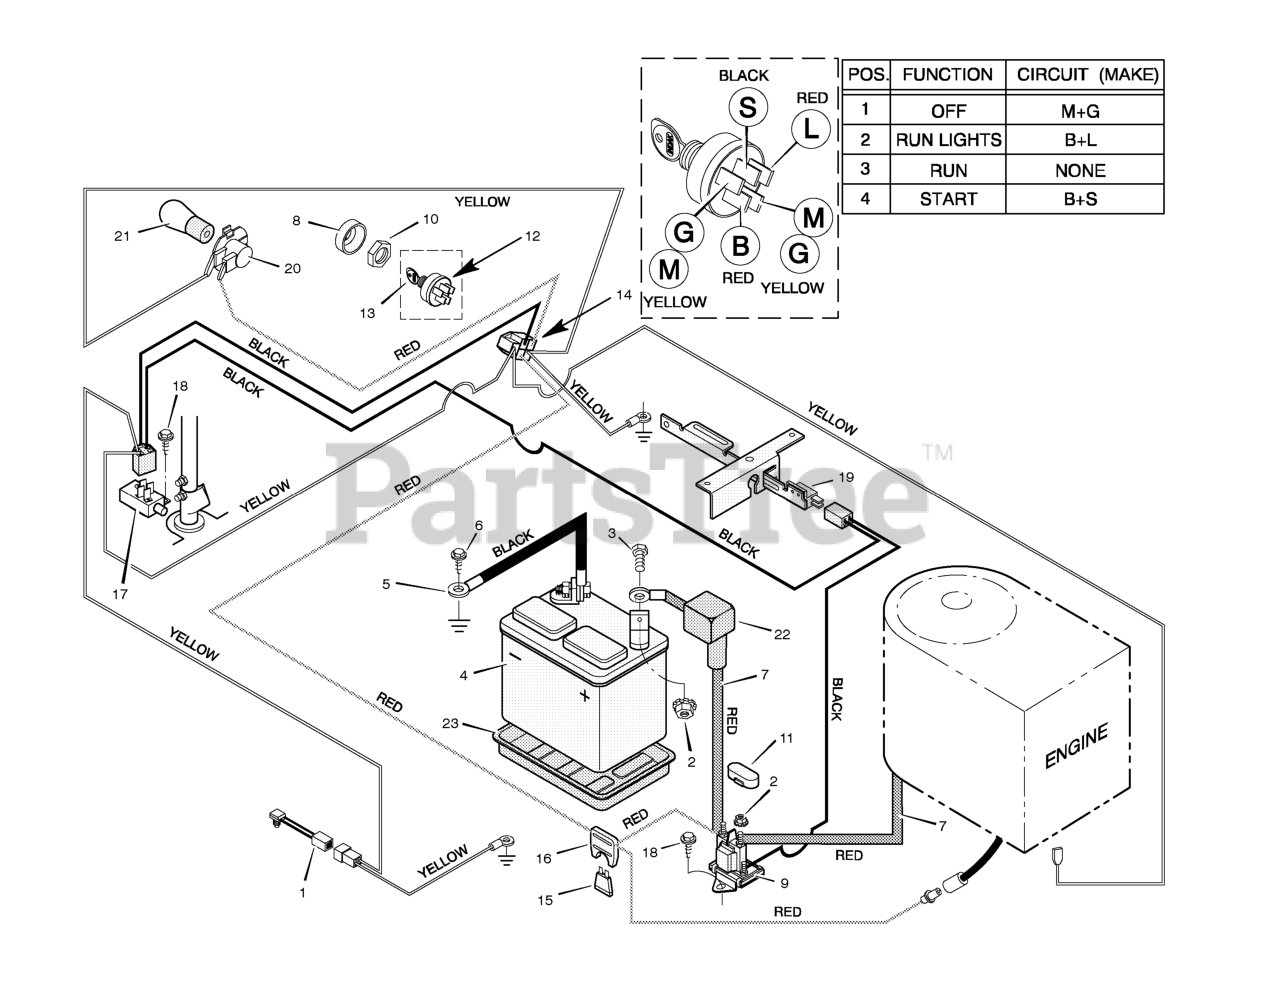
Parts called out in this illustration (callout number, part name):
1	Switch, Seat Sensor
2	Locknut
4	Battery
5	Cable, Battery Ground
7	Cable, Red Battery
8	Cap, Ignition
9	Solenoid
10	Nut, Hex
11	Cover, Solenoid
12	Switch, Ignition
13	Key, Ignition
14	Harness, Chassis Wire
16	Holder, Fuse
17	Switch, Limit
19	Switch, Limit
20	Socket, Light
21	Bulb, Light
22	Cover, Terminal
23	Tray, Battery
